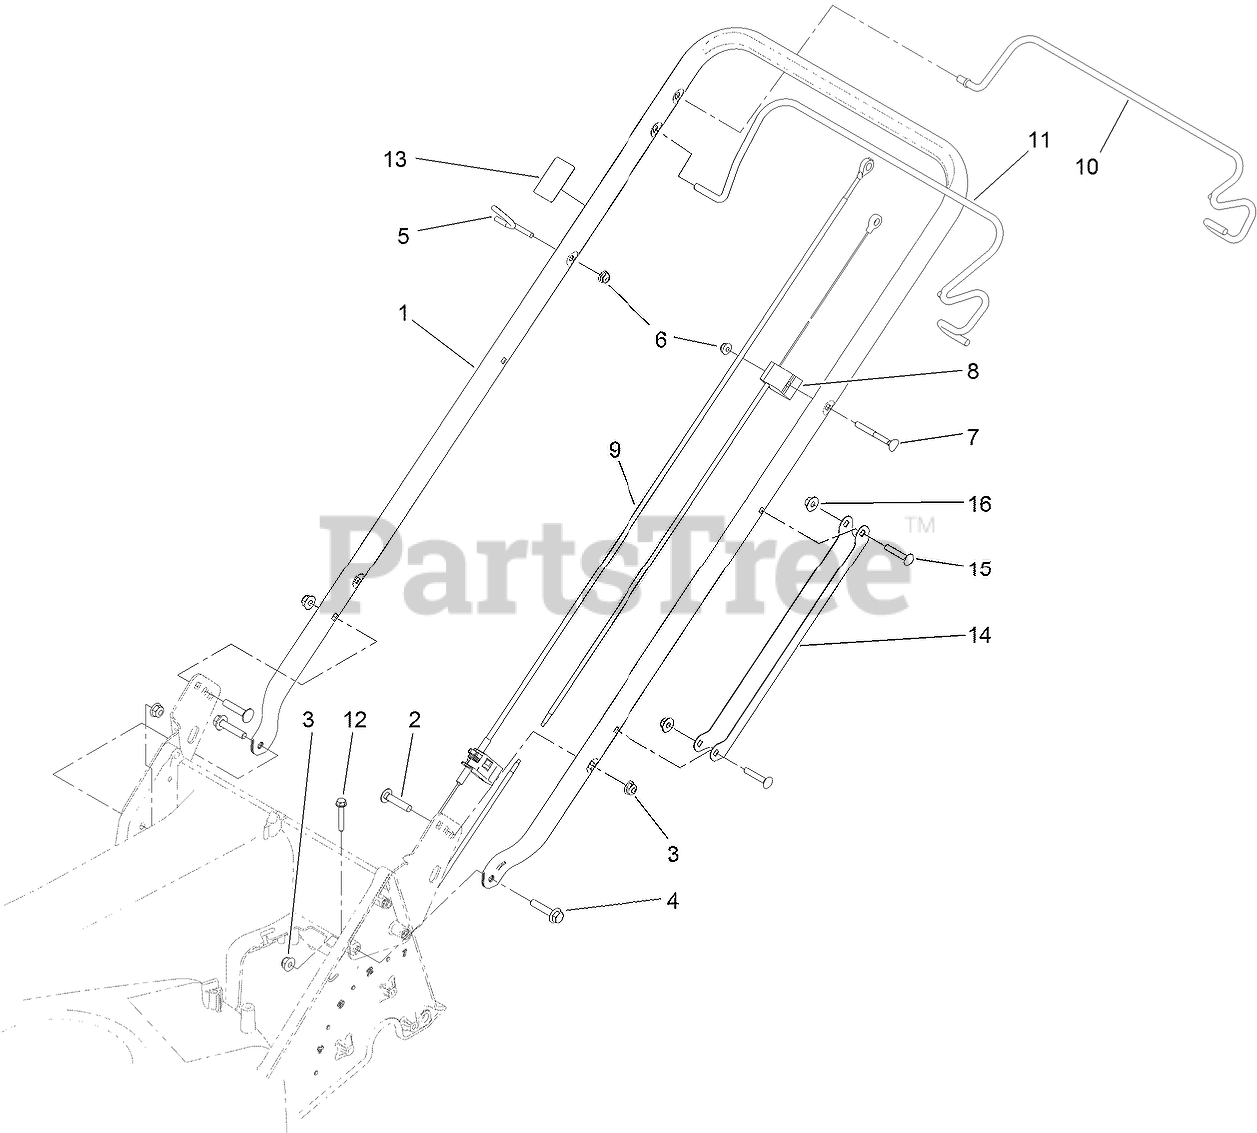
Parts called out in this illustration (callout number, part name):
1	HANDLE
2	BOLT-CARR
3	NUT-HF, NI
4	SCREW-HHF
5	GUIDE-ROPE
6	NUT-HF
7	SCREW-HANDLE
8	CABLE-BRAKE
9	CABLE-TRACTION
10	BAIL-TRACTION
11	BAIL-BRAKE
12	SCREW-HWH
13	DECAL-PRIMER
14	GUARD-CABLE, HANDLE
15	SCREW-CARR
16	NUT-HEX FLG
